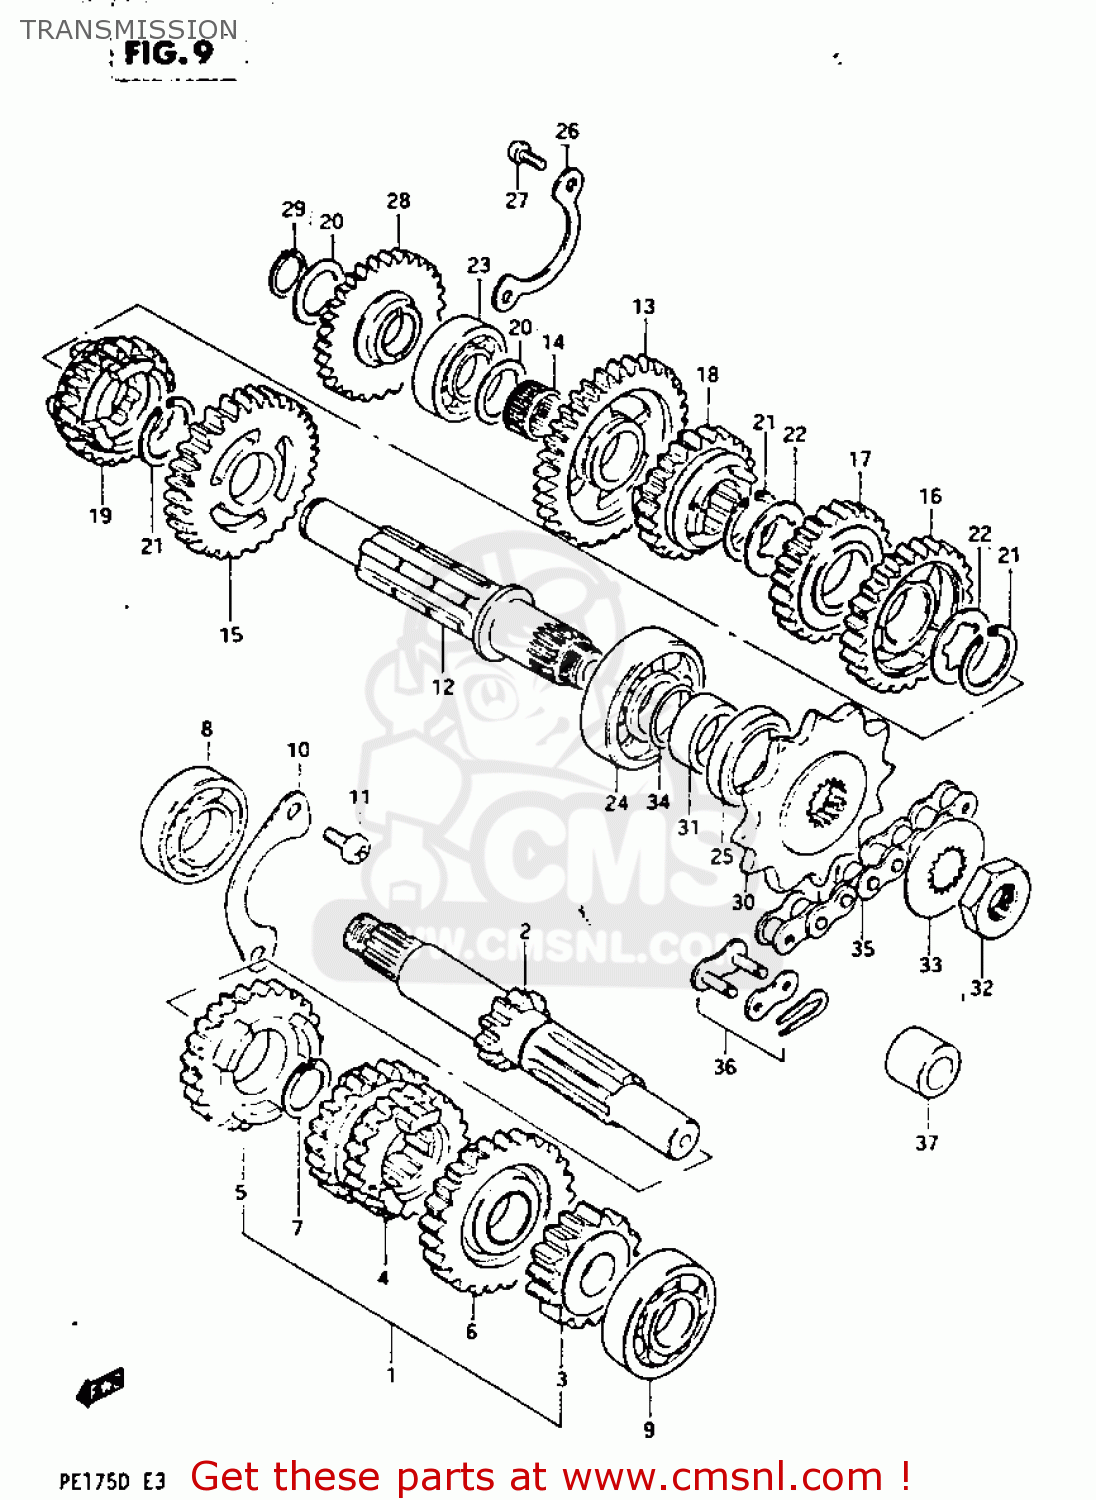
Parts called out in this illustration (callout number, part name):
1	SHAFT ASSEMBLY,COUNTER
2	SHAFT,COUNTER
3	GEAR,SECOND DRIVE
4	GEAR,THIRD DRIVE
5	GEAR,FIFTH DRIVE
6	GEAR,SIXTH DRIVE
7	CIRCLIP
8	BEARING(20X47X14)
9	BEARING
10	RETAINER,CNTR SHAFT BEARING
11	SCREW 6X12
12	SHAFT,DRIVE
13	GEAR,FIRST DRIVEN
14	ROLLER BEARING (15X19X9
15	GEAR,SECOND DRIVEN
16	GEAR,THIRD DRIVEN
17	GEAR,FOURTH DRIVEN
18	GEAR,FIFTH DRIVEN
19	GEAR,SIXTH DRIVEN
20	WASHER,THRUST
21	CIRCLIP
22	WASHER,LOCK
23	BEARING
24	BEARING(20X47X14)
25	SEAL,OIL(25X40X7)
26	PLATE,DRIVESHAFT BEARING
27	SCREW
28	GEAR,KICK STARTER IDLE
29	CIRCLIP,15MM
30	SPROCKET,ENGINE
31	SPACER(20X25X12.5)
32	NUT
33	WASHER,LOCK
34	O RING(D:1,ID:19.5)
35	CHAIN ASSEMBLY,DRIVE
36	JOINT ASSEMBLY,CHAIN
37	SPACER(12X20X15.3)
